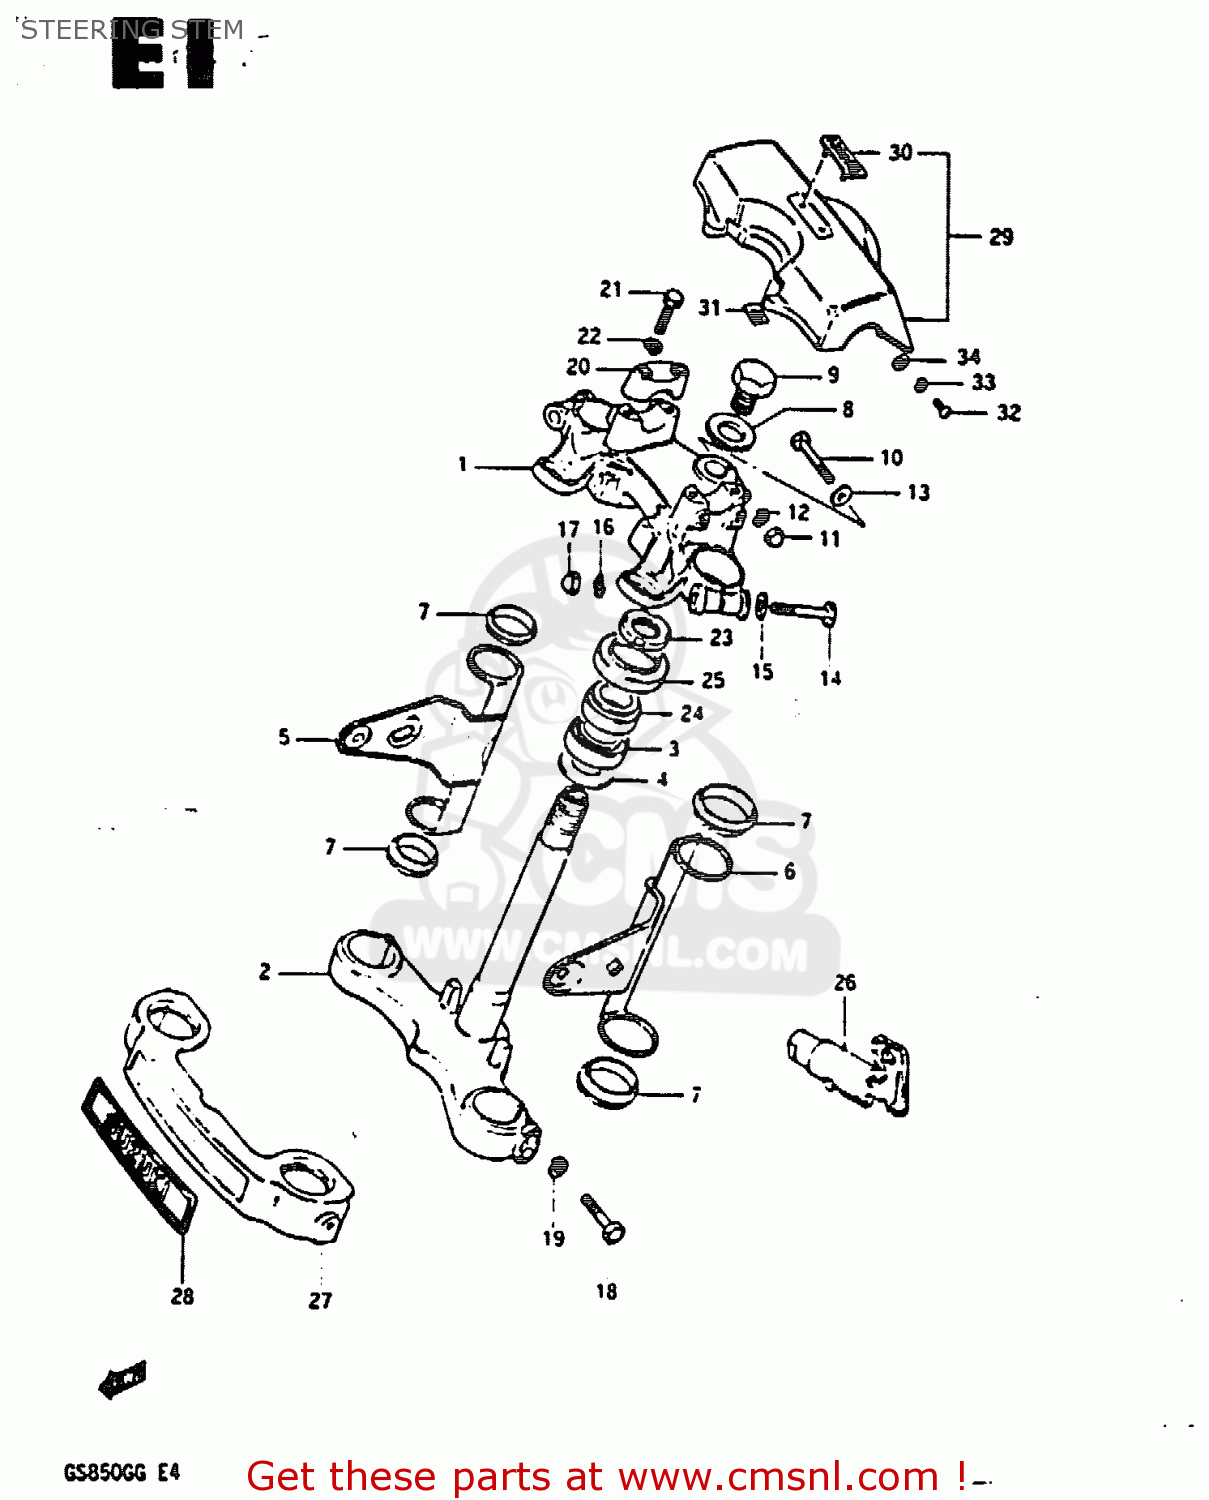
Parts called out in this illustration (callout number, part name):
1	HEAD,STEERING STEM
2	STEM,STEERING
3	BEARING
4	WASHER,THRUST
5	BRACKET,HEADLAMP,RIGHT
6	BRACKET,HEADLAMP,LEFT
7	CUSHION,HEADLAMP BRACKET
8	WASHER,STEERING STEM
9	NUT,STEM HEAD
10	BOLT 8X50
11	NUT
12	LOCK WASHER
13	WASHER
14	BOLT 10X55
15	WASHER
16	LOCK WASHER
17	NUT, LOWER LH
18	BOLT
19	LOCK WASHER
20	HOLDER,HANDLE(BLACK)
21	BOLT
22	LOCK WASHER
23	NUT,STEERING STEM
24	TAPER,ROLLER BEARING
25	DUST SEAL,STEERING UPR
26	LOCK ASSEMBLY,STEERING (NEI
27	COVER,FRONT FORK
28	EMBLEM,FRONT FORK COVER
29	PAD,HANDLEBAR
30	EMBLEM,HANDLE COVER PAD
31	NUT
32	SCREW
33	WASHER,LOCK
34	WASHER,5MM
